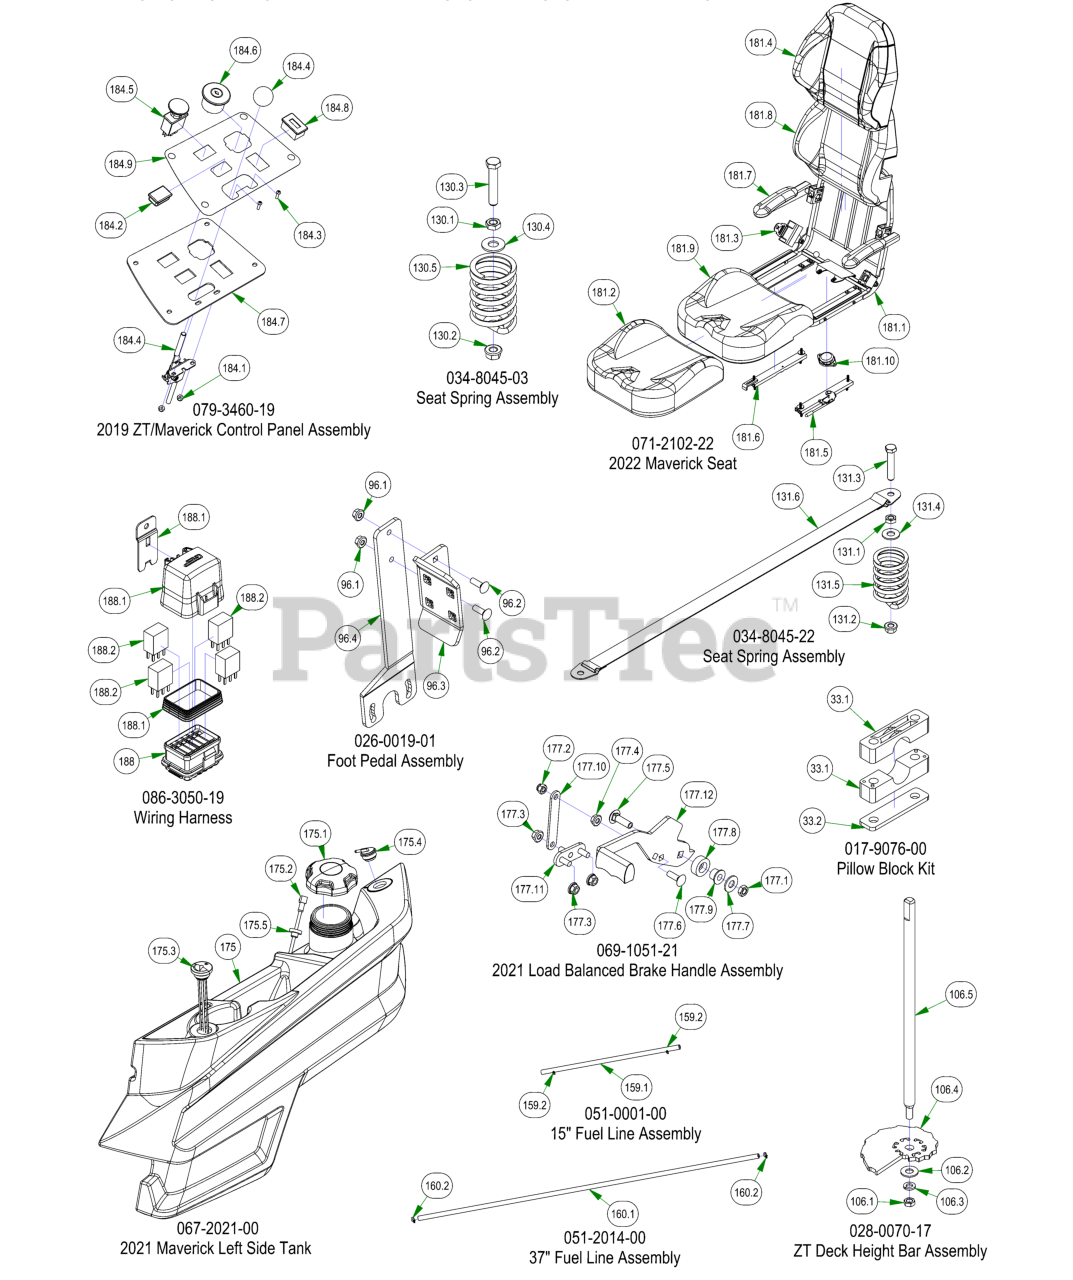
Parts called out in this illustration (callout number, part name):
33	Pillow Block Kit
33.1	Pillow Block MZ
33.2	Pillow Block Strap
96	Foot Pedal Assembly
96.1	5/16-18 NYLON INSERT FLANGE LOCKNUT ZINC
96.2	5/16-18 X 1 CARRIAGE BOLT (GR.8) ZINC
96.3	2017 MZ/ZT Shallow Foot Pedal
96.4	2017 MZ/ZT Deck Pedal Lever
106	ZT Deck Height Bar Assembly
106.1	3/8-24 HEX NUT ZINC YELLOW
106.2	3/8 FLAT WASHER USS (1" OD) ZINC
106.3	3/8 SPLIT LOCKWASHER ZINC
106.4	2017 MZ/ZT Cam Plate
106.5	2017 Deck Height Dial Rod ZT
130	Seat Spring Assembly
130.1	3/8-16 Half Jam Nut
130.2	3/8-16 HEX SERRATED FLANGE NUT HARD/ZINC
130.3	3/8-16 X 2 HEX CAP SCREW (GR.5) ZINC
130.4	3/8 FLAT WASHER USS (1" OD) ZINC
130.5	Seat Spring
131	Seat Spring Assembly
131.1	3/8-16 Half Jam Nut
131.2	3/8-16 HEX SERRATED FLANGE NUT HARD/ZINC
131.3	3/8-16 X 2 HEX CAP SCREW (GR.5) ZINC
131.4	3/8 FLAT WASHER USS (1" OD) ZINC
131.5	Seat Spring
131.6	Seat Strap with Buckles
159	15" Fuel Line Assembly
159.1	1/4 Fuel Line
159.2	1/4 Fuel Hose Clamp
160	37" Fuel Line Assembly
160.1	37" 1/4 Fuel Line
160.2	1/4 Fuel Hose Clamp
175	2021 Maverick Left Side Tank
175.3	Fuel Gauge w/Grommet
175.4	Rollover Valve W/Grommet
175.5	Pick-Up Grommet
177	2021 Load Balanced Brake Handle Assembly
177.1	3/8-16 HEX JAM 2-WAY REVERSIBLE CENTER LOCKNUT ZINC
177.2	5/16-18 NYLON INSERT CAP LOCKNUT ZINC (BLK CAP)
177.3	5/16-18 NYLON INSERT FLANGE LOCKNUT ZINC
177.4	5/16-18 HEX SERRATED FLANGE NUT HARD/ZINC
177.5	3/8-16 X 1-1/4 CARRIAGE BOLT ZINC
177.6	5/16-18 X 1 CARRIAGE BOLT (GR.8) ZINC
177.7	3/8 FLAT WASHER USS (1" OD) ZINC
177.8	2015 Brake Lever Spacer
177.9	.377 ID X .625 OD X .500 HGT X .880 FLNG DIA X .060 FLNG THK
177.10	Brake Cable Extension Plate
177.11	Brake Load Balancer Lower Weldment
177.12	Load Balanced Brake Handle with Grip
181	2022 Maverick Seat
181.1	400 Series Universal Mount Frame 3/4"
181.2	Seat Cover
181.3	Seat Belt Set
181.4	Back Cover
181.5	Bad Boy Seat Slide
181.6	Bad Boy Slave Slide
181.7	Poly Pad w/ Shorter AFT Bracket
181.8	Seat Back Mold
181.9	Seat Bottom Mold
181.10	Seat Switch
184	2019 ZT/Maverick Control Panel Assembly
184.1	10-24 Nylon Insert Locknut Zinc Orange Nylon
184.2	Light Plug
184.3	10-24 X 5/8 BS Button Head Bolt
184.4	Throttle Lever Assembly
184.5	PTO Engager
184.6	Ignition Switch
184.7	2014 ZT Control Panel
184.8	Tachometer
184.9	Rambler Instrument Panel Decal
188	Wiring Harness
188.1	Relay Block Cover Replacement Kit
